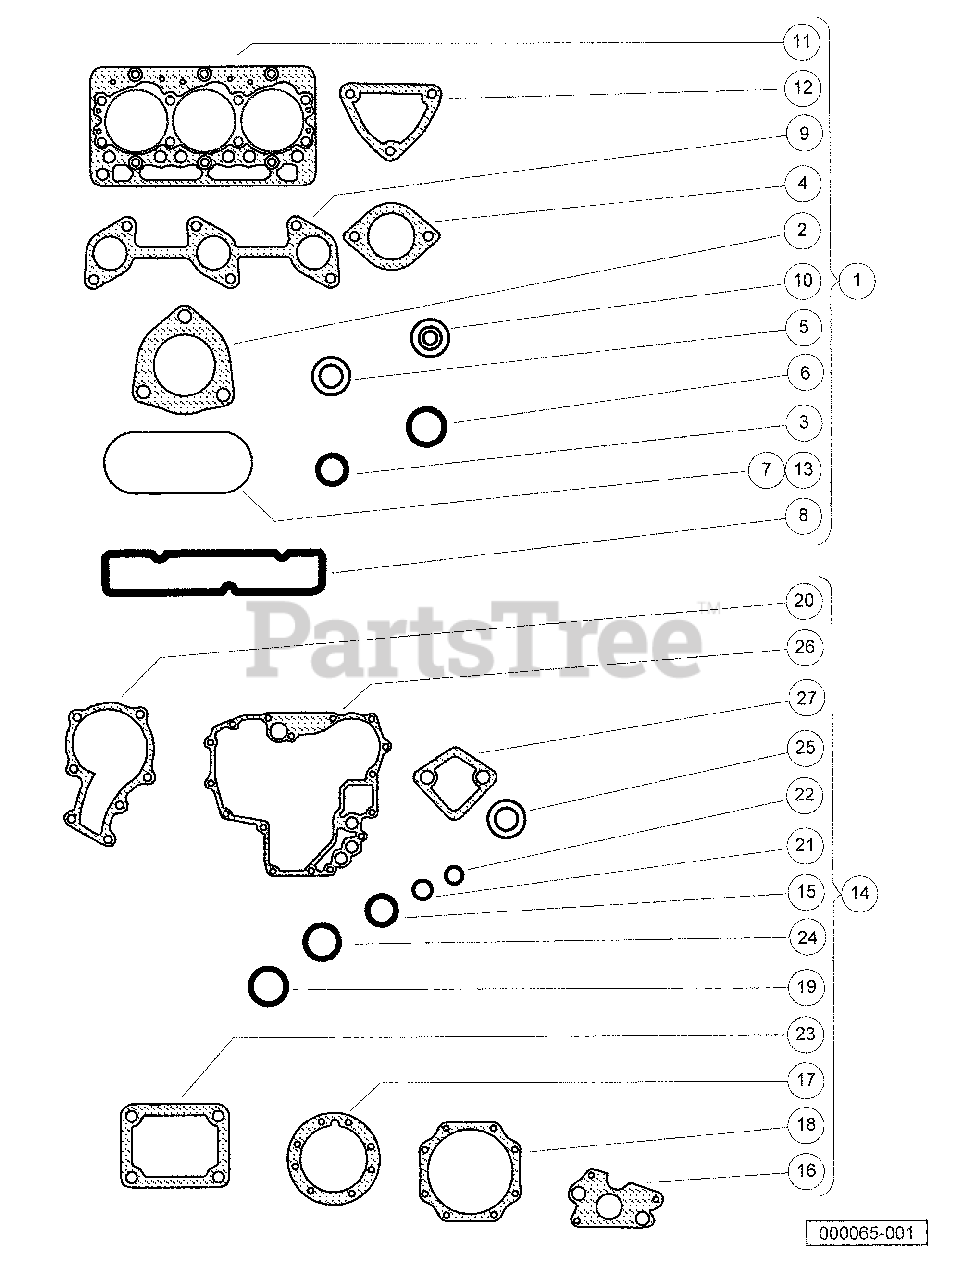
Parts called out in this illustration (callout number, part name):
1	Kit, Gasket Upper, D722
2	Gasket, Exhaust Diesel
3	O Ring, 8 X 7
4	Gasket, Thermostat
5	Gasket, 6 X 10
6	O Ring, 30 X 36
7	Gasket, Head Cover
8	Gasket, Intake Manifold
9	Gasket, Ex-manifold
10	Seal, Valve Stem
11	Gasket, Cylinder Head
12	Gasket, Water Flange
13	Gasket, Cylinder Head Cover
14	Kit, Gasket Lower, D722
15	O Ring, 18 X 13
16	Gasket, Oil Pump
17	Gasket, Bearing Case
18	Gasket, Cover
19	O Ring, 23 X 26
20	Gasket, Water Pump, D722
21	O Ring, 19 X 16
22	O Ring, 9 X 7
23	Gasket, Control Plate
24	O Ring, 20 X 17
25	Gasket, Idle Apparatus, Rear
26	Gasket, Gearcase, D722
27	Gasket, Fuel Pump, D722
